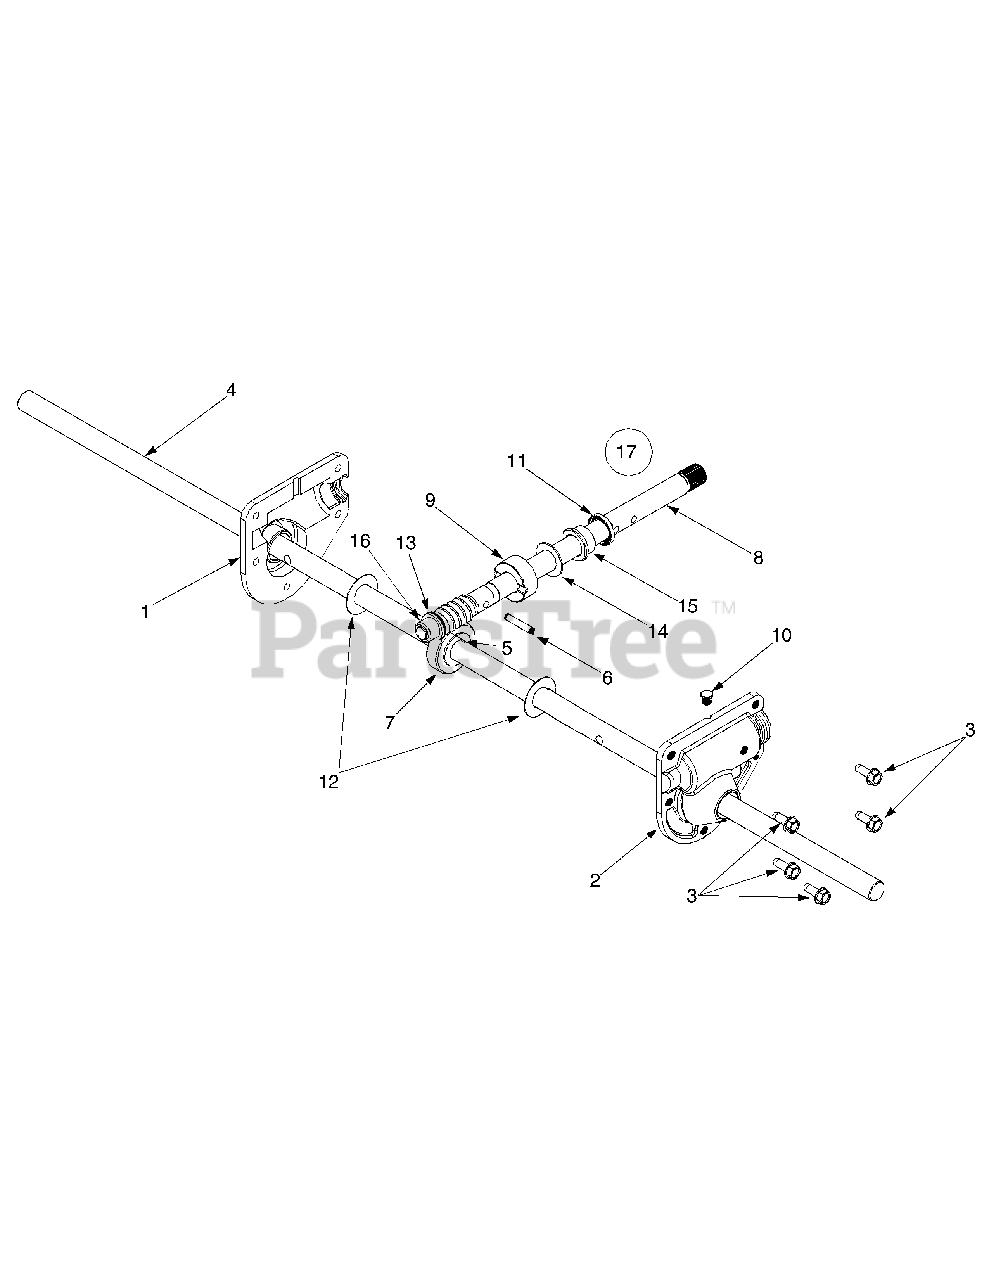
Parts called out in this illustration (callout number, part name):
1	RH Housing
2	LH Housing
3	Self Tapping Screw, 1/4-20 x .75
4	Spiral Axle, 28"
5	Hi-Pro Key, 3/16 x 5/8
6	Spring Spiral Pin, .25 x 1.25
7	Worm Gear, 20-tooth
8	Worm Shaft
9	Thrust Collar
10	Grease Plug
11	Grease Seal
12	Flat Washer, .76 x 1.5 x .030
13	Flat Washer, .508 x 1.0 x .020
14	Flat Washer, .76 x 1.5 x .060
15	Flange Bearing, .75 x 1.0 x .59
16	Flange Bearing, .503 ID x .75 OD
17	Gear Ass’y Complete, 28"
